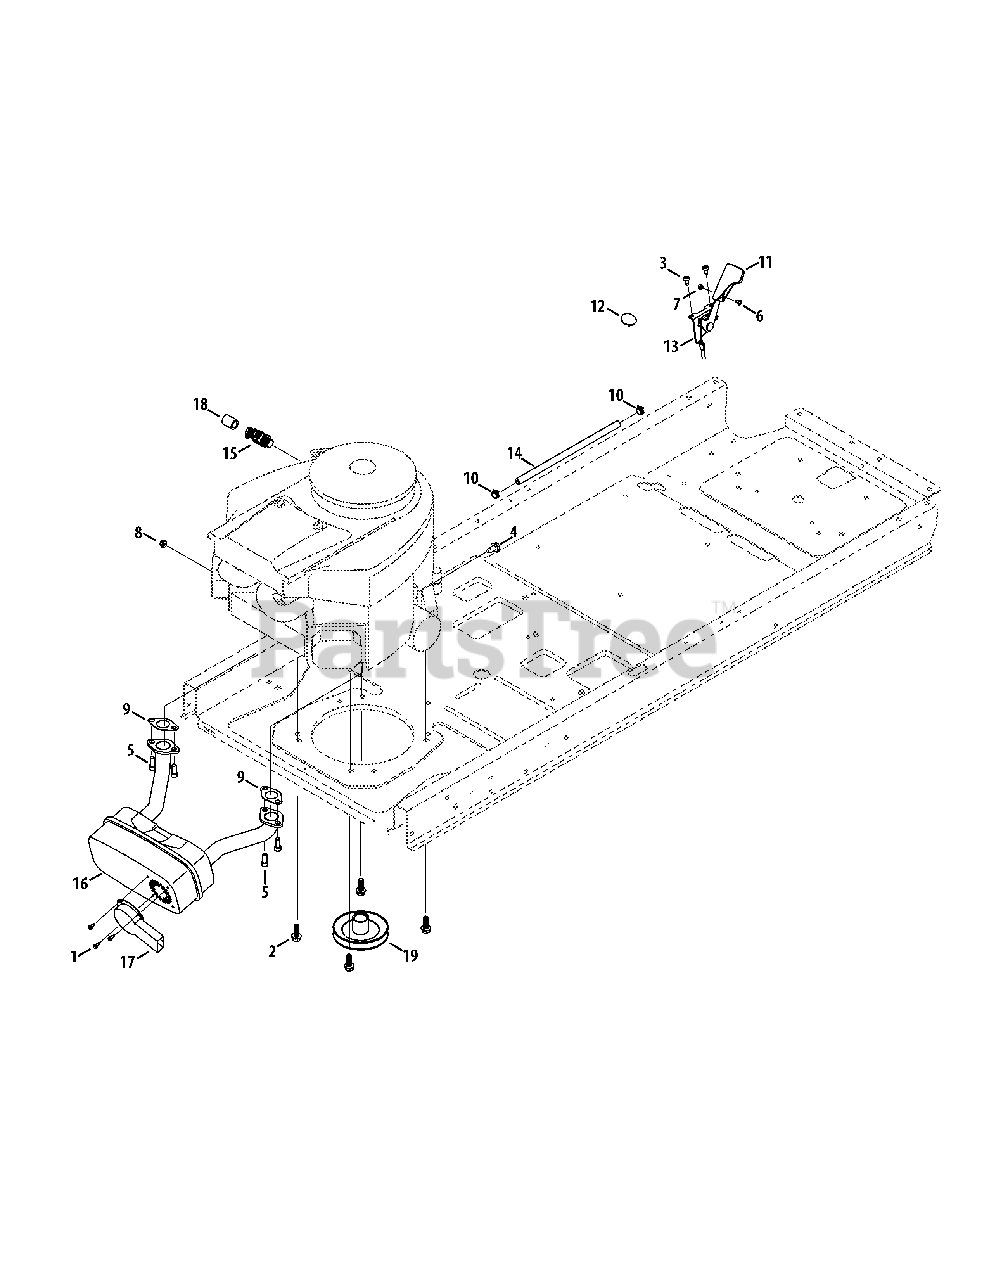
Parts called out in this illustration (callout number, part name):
1	Hex Washer Screw, #8-18 x .500
2	Hex Washer Screw, 3/8-16 x 1.000
3	Screw, 1/4-20 x .5
4	Hex Washer Screw, 1/4-20 x .500
5	Screw, 5/16-18 x .750
6	Machine Screw, #8-32 x .375
7	Hex Nut, #8-32
8	Flange Lock Nut, 1/4-20
9	Exhaust Gasket
10	Hose Clamp, .490
11	Throttle Knob
12	Choke Plug
13	Throttle/Choke Cable
14	Low-Permeation Fuel Hose
15	Oil Drain
16	Muffler
17	Muffler Deflector
18	Oil Drain Extension Hose
19	Engine Pulley
